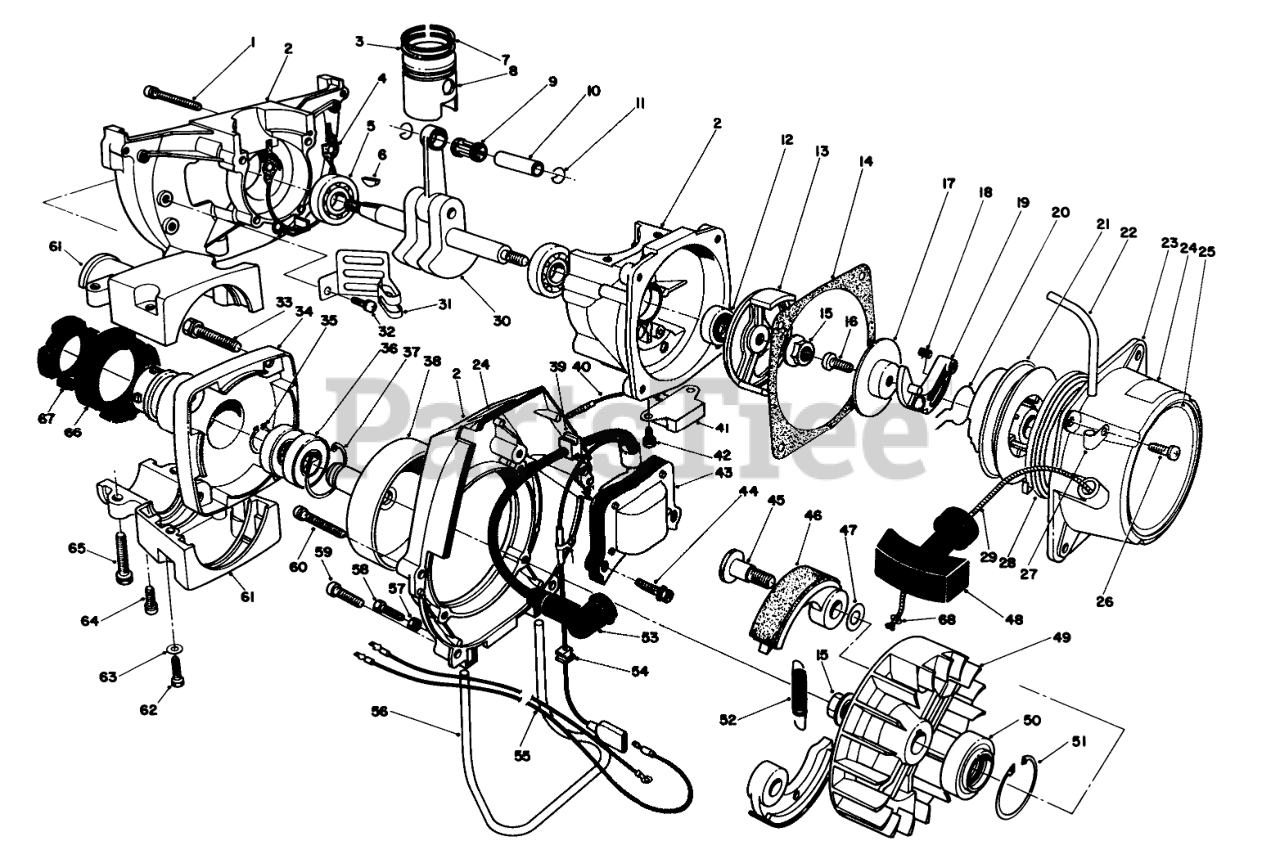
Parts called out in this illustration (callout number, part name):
1	SCREW & WASHER
2	Crankcase (Incl. Ref. #1, & 59)
3	RING,PISTON
4	GASKET,CASE
5	BALL BEARING
7	RING,PISTON
8	PISTON SET
9	BEARING, NEEDLE
10	PIN, PISTON
11	CLIP, PISTON PIN
12	OIL SEAL
13	PULLEY, STARTER
14	GASKET, STARTER
16	Screw
17	PLATE, FRICTION
18	SPRING, RETURN
19	RATCHET
20	SPRING, FRICTION
22	Tube-Fuel
23	Recoil-Starter (Incl. Ref. #13, 16-21, 24, 25, 28, 29, &48)
24	DECAL HOT
25	TORO DECAL
26	Screw
27	Clamp
28	SPRING, SPIRAL
29	Rope-Starter
30	Crankshaft (Incl. Ref. #6&9)
31	Clamp
32	Screw & Washer
34	CASE, CLUTCH
35	SNAP RING
36	BALL BEARING
37	SNAP RING
38	DRUM, CLUTCH
39	Grommet
40	WIRE, LEAD
41	UNIT, TRANSISTOR
42	SCREW & WASHEROR
43	COIL, IGNITION
44	BOLT AND WASHER
45	BOLT,CLUTCH
46	Shoe-Clutch
47	WASHER
48	Knob-Starter
49	FLYWHEEL
50	OIL SEAL
51	SNAPRING
52	SPRING
53	CAP-PLUG
54	GROMMET
55	WIRE,LEAD
56	TANK GUARD
59	Screw
60	Screw
61	VV2DER
63	Washer
64	SCREW & WASHER
65	BOLT-WASHER/ENG
66	RUBBER, CUSHION (A)
67	RUBBER, CUSHION (B)
68	WASHER
